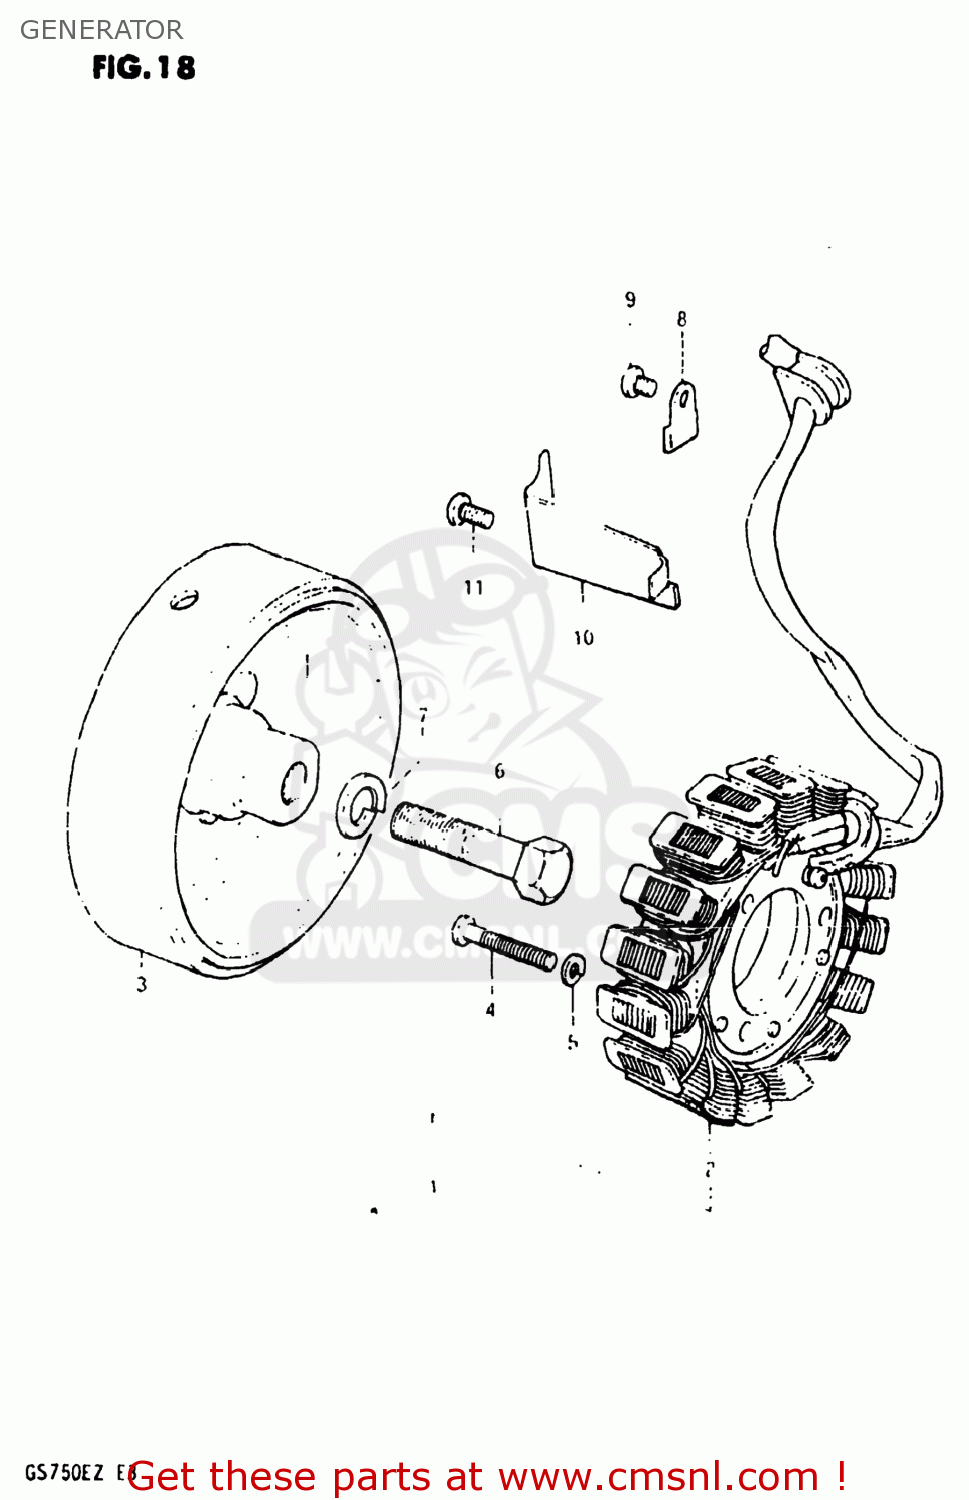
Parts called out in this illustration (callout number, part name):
1	GENERATOR ASSEMBLY
2	STATOR ASSEMBLY
3	ROTOR ASSEMBLY
4	SCREW
5	LOCK WASHER
6	BOLT 12X45
7	WASHER,LOCK 12
8	CLAMP,GENERATOR LEAD WIRE
9	SCREW
10	CLAMP,GENERATOR LEAD WIRE
11	SCREW
